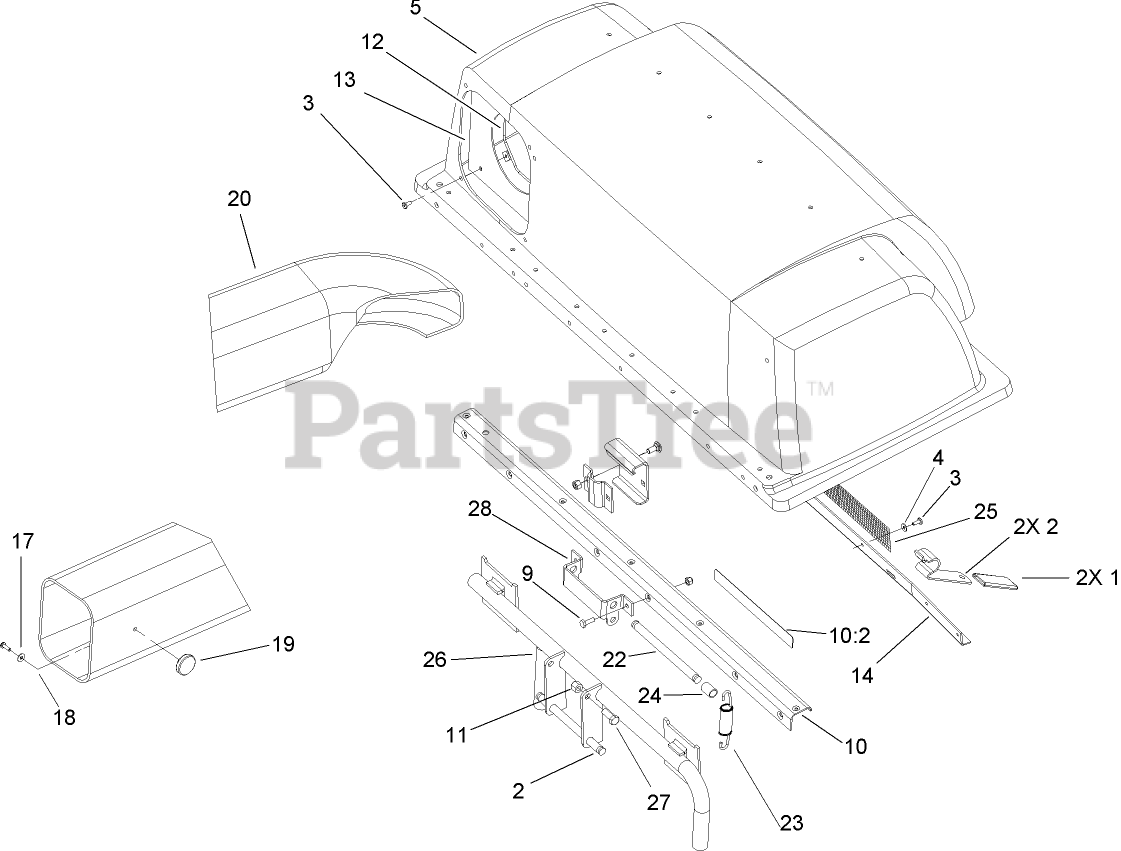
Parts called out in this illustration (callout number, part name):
2	LATCH-BAGGER, TOP
3	RIVET-BLIND
4	WASHER-FLAT
5	TOP-BAGGER
9	SCREW-HH
10	STIFFENER ASM
10:2	DECAL-CAUTION
11	NUT-LOCK, NI
12	CLAMP-SEAL
13	SEAL-CHUTE
14	SUPPORT-SCREEN
17	SCREW-PPHTF
18	WASHER-PLAIN
20	CHUTE-DISCHARGE
22	PIN-SPRING
23	SPRING-EXTENSION
24	SPACER
25	SCREEN-BAGGER
26	FRAME ASM
27	SCREW-HH
28	HINGE-BAG, TOP
